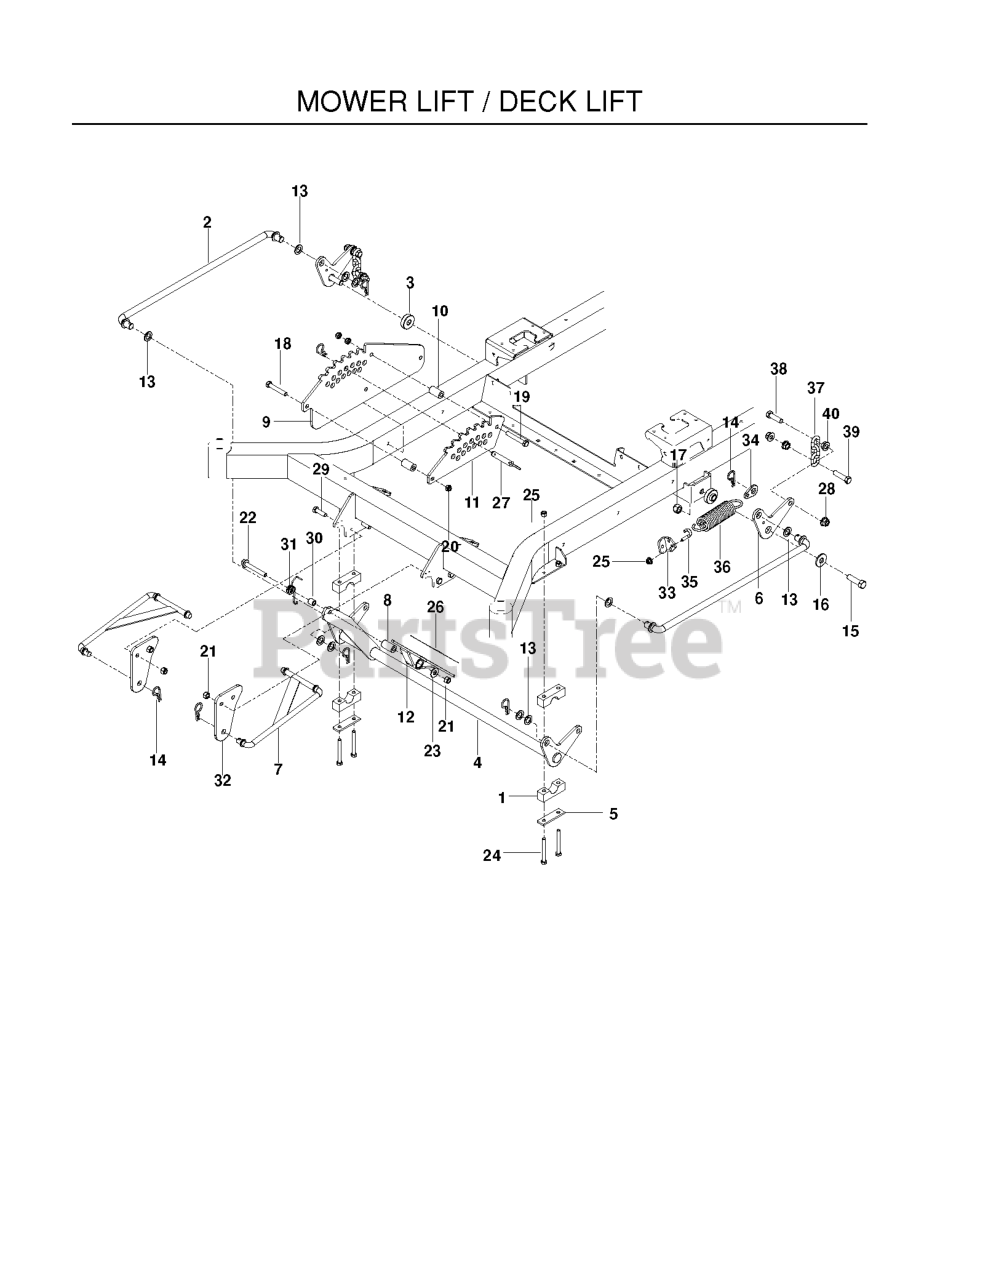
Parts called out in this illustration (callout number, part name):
1	PILLOW BLOCK
2	CROSS LINK
3	IDLER SPACER
4	SHAFT, LIFT, DECK
5	REINFORCEMENT BAR
6	BELLCRANK, REAR LIFT
7	STRUT LINKAGE
8	BUSHING, SLEEVE
9	PLATE, HEIGHT, MAIN, BLUE
10	DECK LIFT SPACER
11	PLATE, HEIGHT, BLUE
12	PEDAL, FOOT, WELDMENT
13	BUSHING
14	PIN, COTTER 1 3/4
15	HCS 1/2-13 X 1 3/4 GR 8
16	WASH USS FLAT 1/2
17	NUT 1/2-13 HEX NYLOC ZD
18	HCS 3/8C X 2 1/4
19	HCS 3/8C X 2 1/2
20	NUT HEX 3/8-16 NYLON, THIN
21	NUT 3/8-16 NYLOC
22	HHFS 3/8-16 X 2 3/4
23	WASHER 3/8 FLAT
24	HCS 5/16C X 2-3/4
25	5/16-18 NYLOC FLANGE NUT
26	FOOT PAD
27	HITCH PIN
28	NUT 7/16-14 HEX WHIZ LK
29	HCS 3/8C X 1 1/4
31	SPRING, TORSION
32	MOUNT, STRUT
33	MOUNT, SPRING
34	TAB, SPRING
37	LIFT CHAIN - 3 LINK
38	HCS 7/16C X 1 1/2
39	HCS 7/16 - 14 X 1 3/4
40	NUT 7/16C WHIZ
